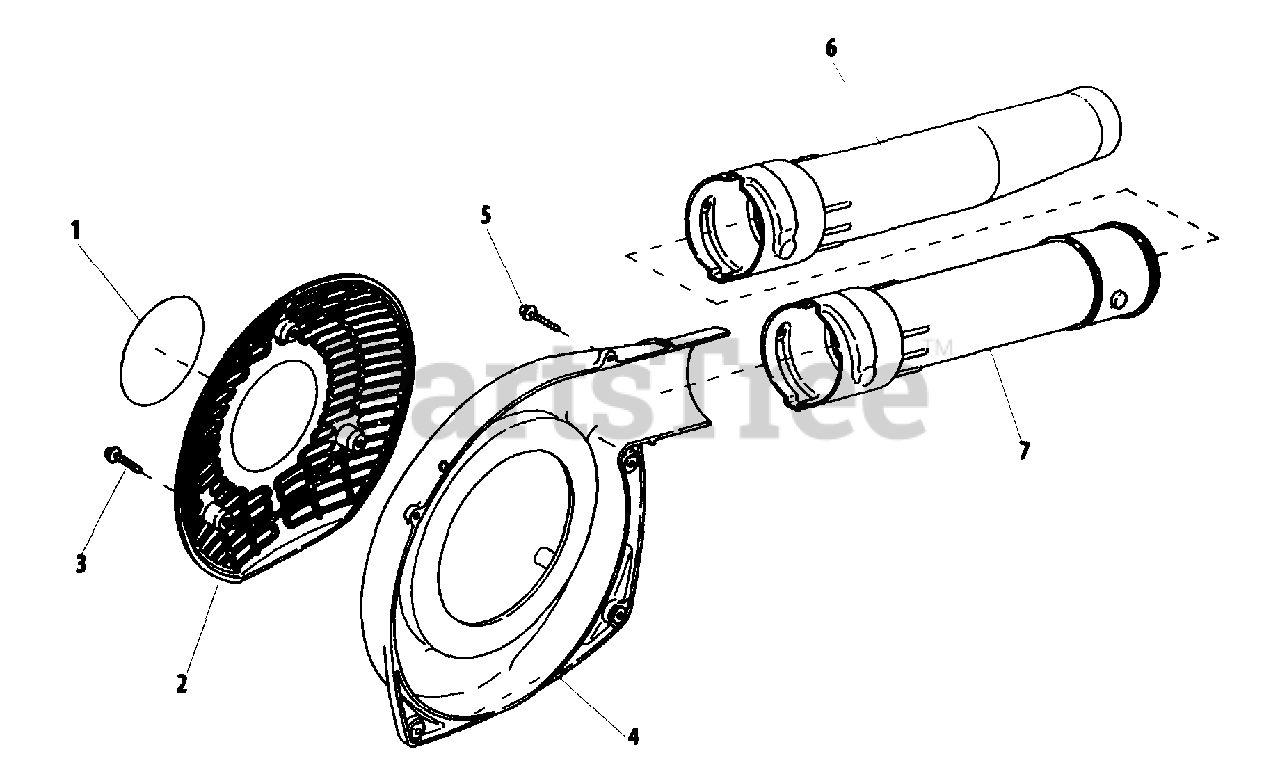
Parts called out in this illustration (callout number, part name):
1	LABEL - MODEL
2	COVER, INTAKE
3	SCREW
4	COVER, FAN - LEFT
5	SCREW
6	NOZZLE
7	PIPE
